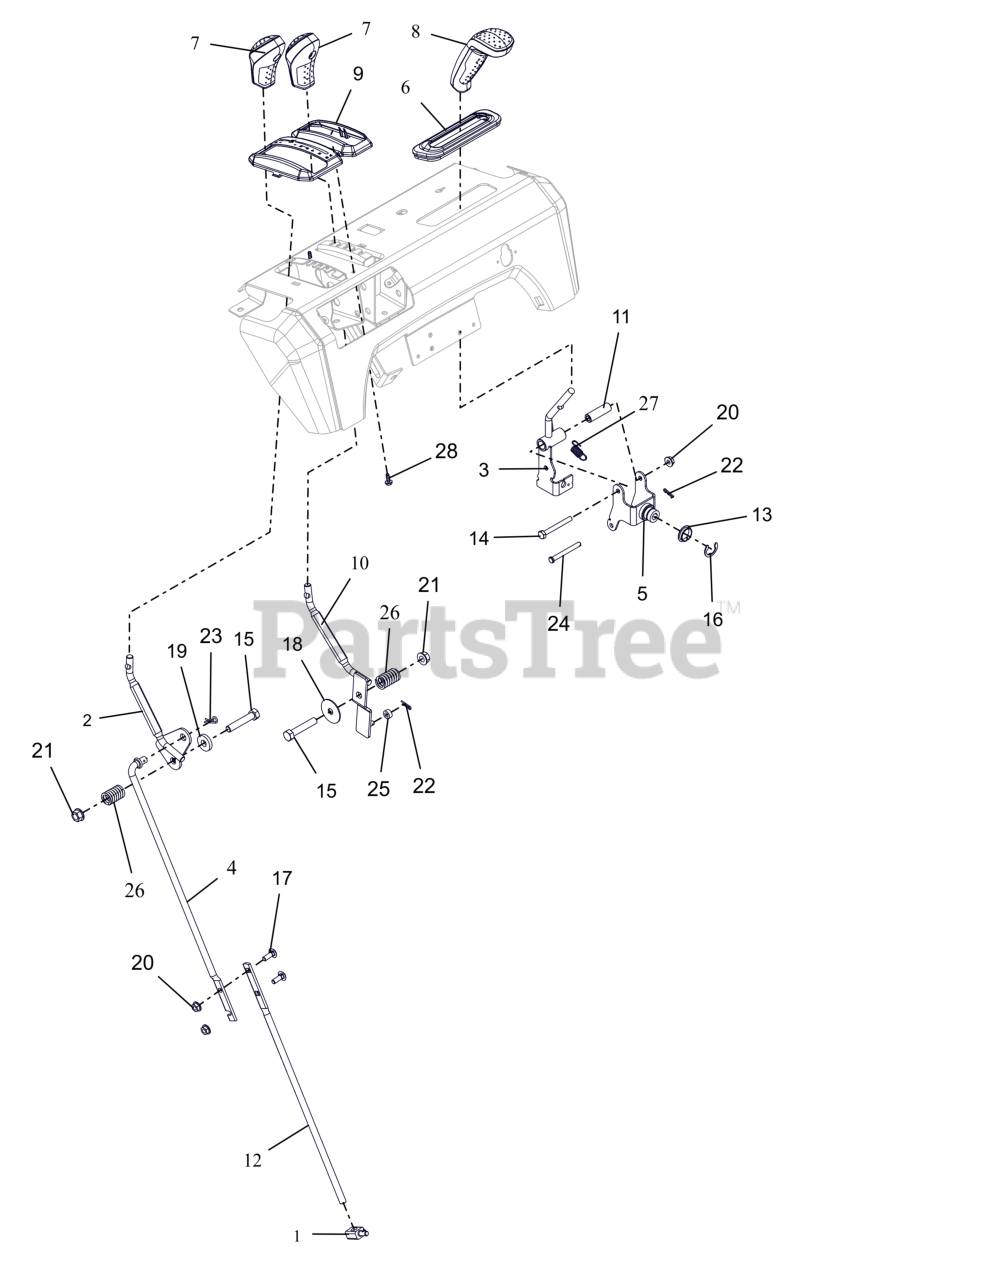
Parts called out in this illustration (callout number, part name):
1	PIVOT,SHIFT ROD .375-16(TRUNN)
2	WELDMENT,LG DASH SPEED CONTROL
3	WELDMENT, CONTROL LEVER
4	ROD, SHIFT - UPPER
5	WELDMENT, CONTROL BRACKET
6	GROMMET, BOOT, QUICK TURN
7	KNOB, CONTROL, DASH
8	HANDLE, QUICK TURN, ASM
9	BEZEL, SHIFT - FRICTION SNOW
10	WELDMENT,LG DASH DEFL CONTROL
11	BSHG, SLV .265X.505X1.665
12	ROD, SHIFT-LOWER (LG DASH DLX)
13	BUSHING, POLYLINER-.75 SNAPIN
14	BLT,HEX .25-20X2.25 G5 ZCC
15	BLT,HEX .38-16X2.00 G5 ZCC
16	E-RING .750X.050
17	BLT, RHSN .25-20X.750 G5 ZCC
18	WSHR,FLT .380X1.50X.062 ZCC
19	WSHR, FLT .406X1.00X.188 ZCC
20	NUT-LK-CTR-FLG .25-20 ZC120
21	NUT-LK-TOP-FLG .38-16 ZC120
22	PIN, HAIR #178 .06X.77 ZCC
23	PIN, HAIR #213 .08X1.19 ZCC
24	PIN, CLEVIS - .25 X 2.25 ZCC
25	BSHG-SLV .265X.500X.219
26	SG-COMP .125X.781X1.250
27	SPRING-EXT .047X.438X1.45
28	SCR, PLASTIC #10X.50
